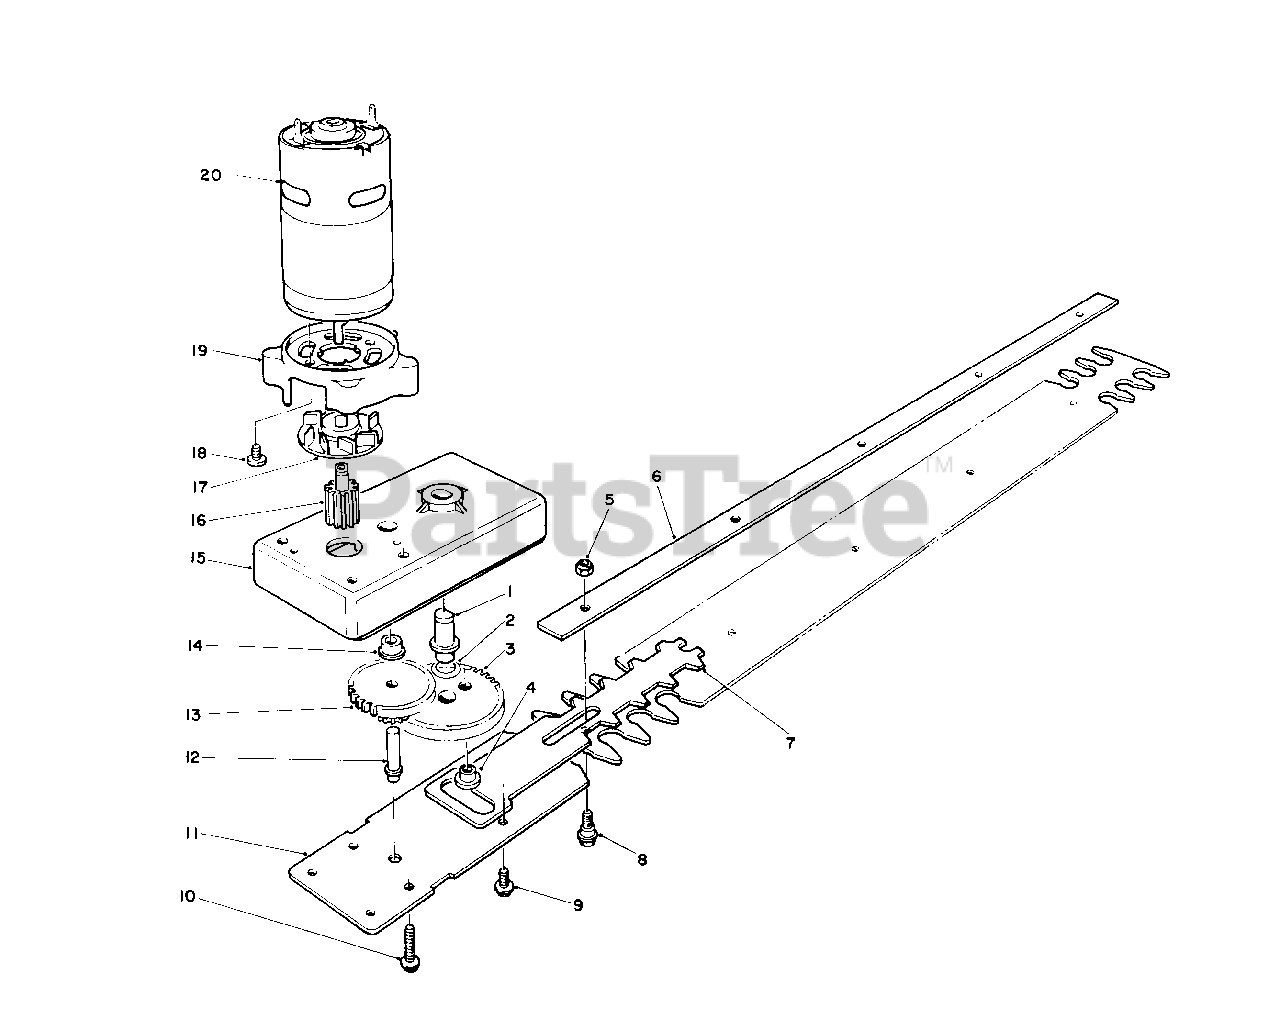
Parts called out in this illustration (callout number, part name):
1	Shaft-Driver
2	Washer-Wave
3	Gear-Drive
4	Bushing-Gear Drive
5	Nut-Lock
6	Retainer-Blade
7	Blade-Cutting
8	Bolt-Blade
9	Screw-Hex Washer Hd.
10	Screw-Hex Washer Hd.
11	Blade-Bottom
12	Shaft-Idler
13	Gear-Idler
14	Bearing-Idler
15	Housing (Incl.Ref.#1&14)
16	Gear-Motor
17	Fan-Motor
18	Screw-Phillips Hd. Pan
19	Support-Motor
20	Motor (Incl.Ref.#16-19)
